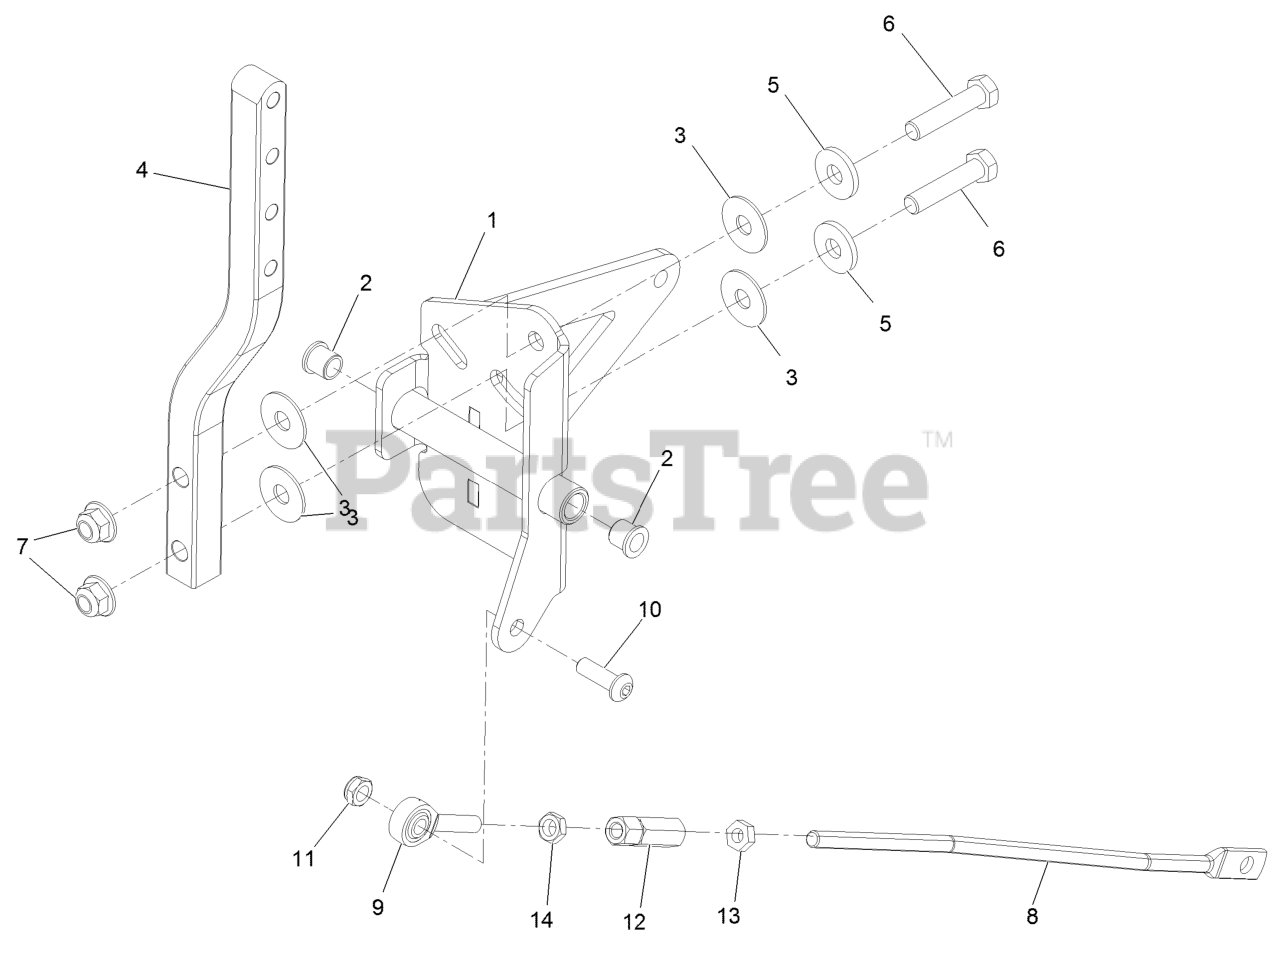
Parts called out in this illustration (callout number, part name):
1	LH CONTROL PIVOT ASM
2	BEARING
3	WASHER-PLASTIC
4	ARM-MOTION CONTROL
5	WASHER
6	SCREW-HH
7	NUT-HF, NI
8	LINK,MOTION CONTROL
9	BEARING-ROD END, LH
10	SCREW-HSBH
11	NUT-LOCK, NI
12	NUT-ROD ADJUSTMENT
13	NUT-JAM
14	NUT-JAM
